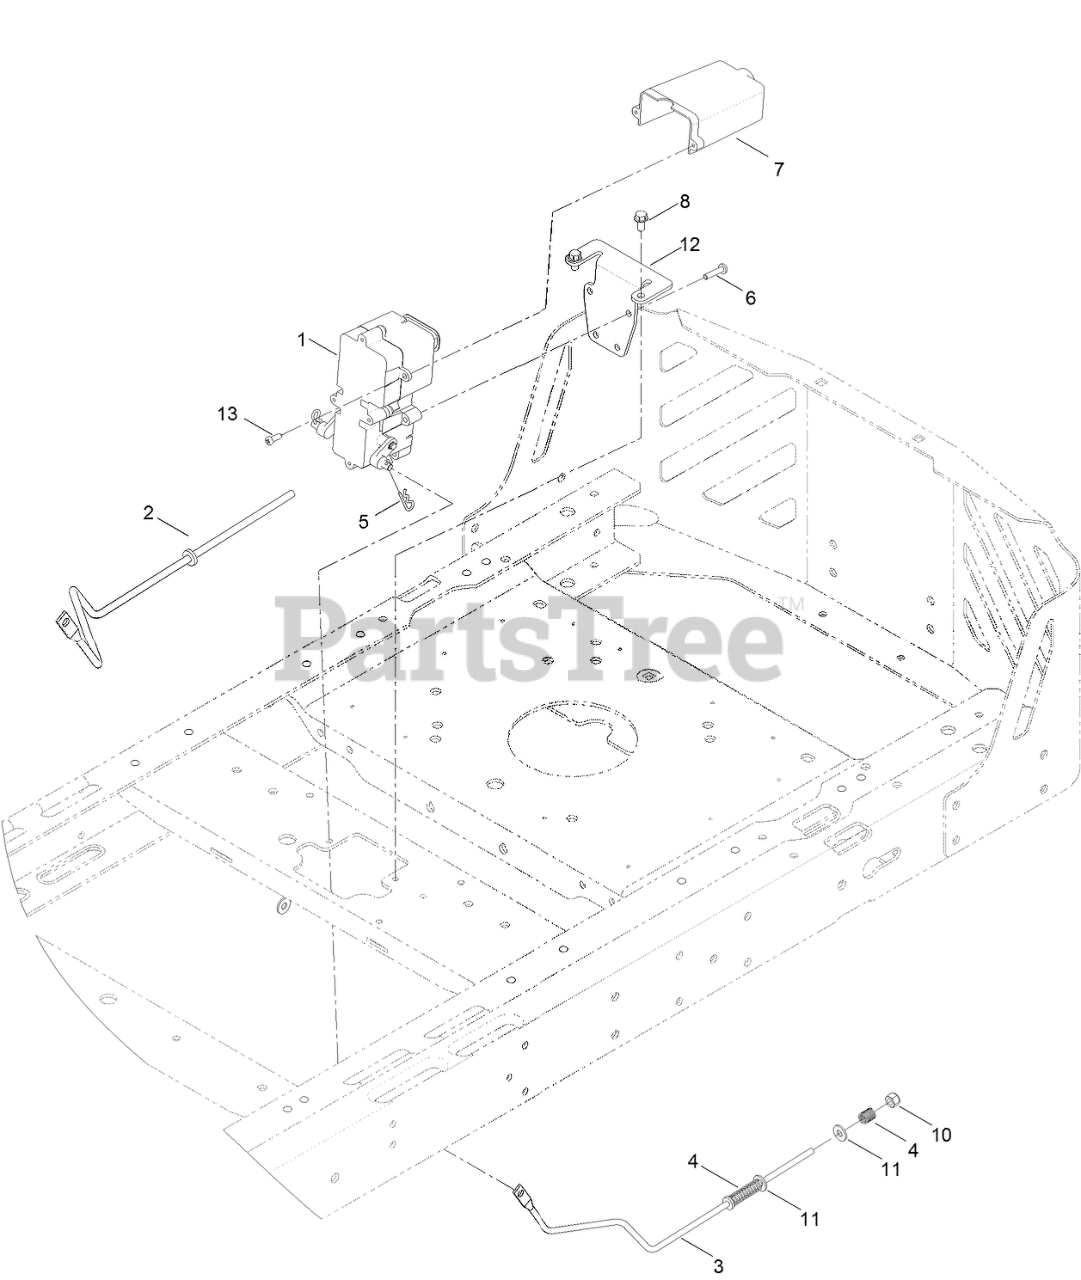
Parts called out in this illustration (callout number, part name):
1	BRAKE BOX ASM
2	ROD-BRAKE, RH
3	ROD-BRAKE, LH
4	SPRING-COMPRESSION
5	PIN-COTTER
6	SCREW-PPH
7	COVER-CONNECTOR
8	SCREW-HWH
10	NUT-LOCK, NI
11	WASHER
12	BRACKET-MOUNT, BRAKE
13	SCREW-PPH
